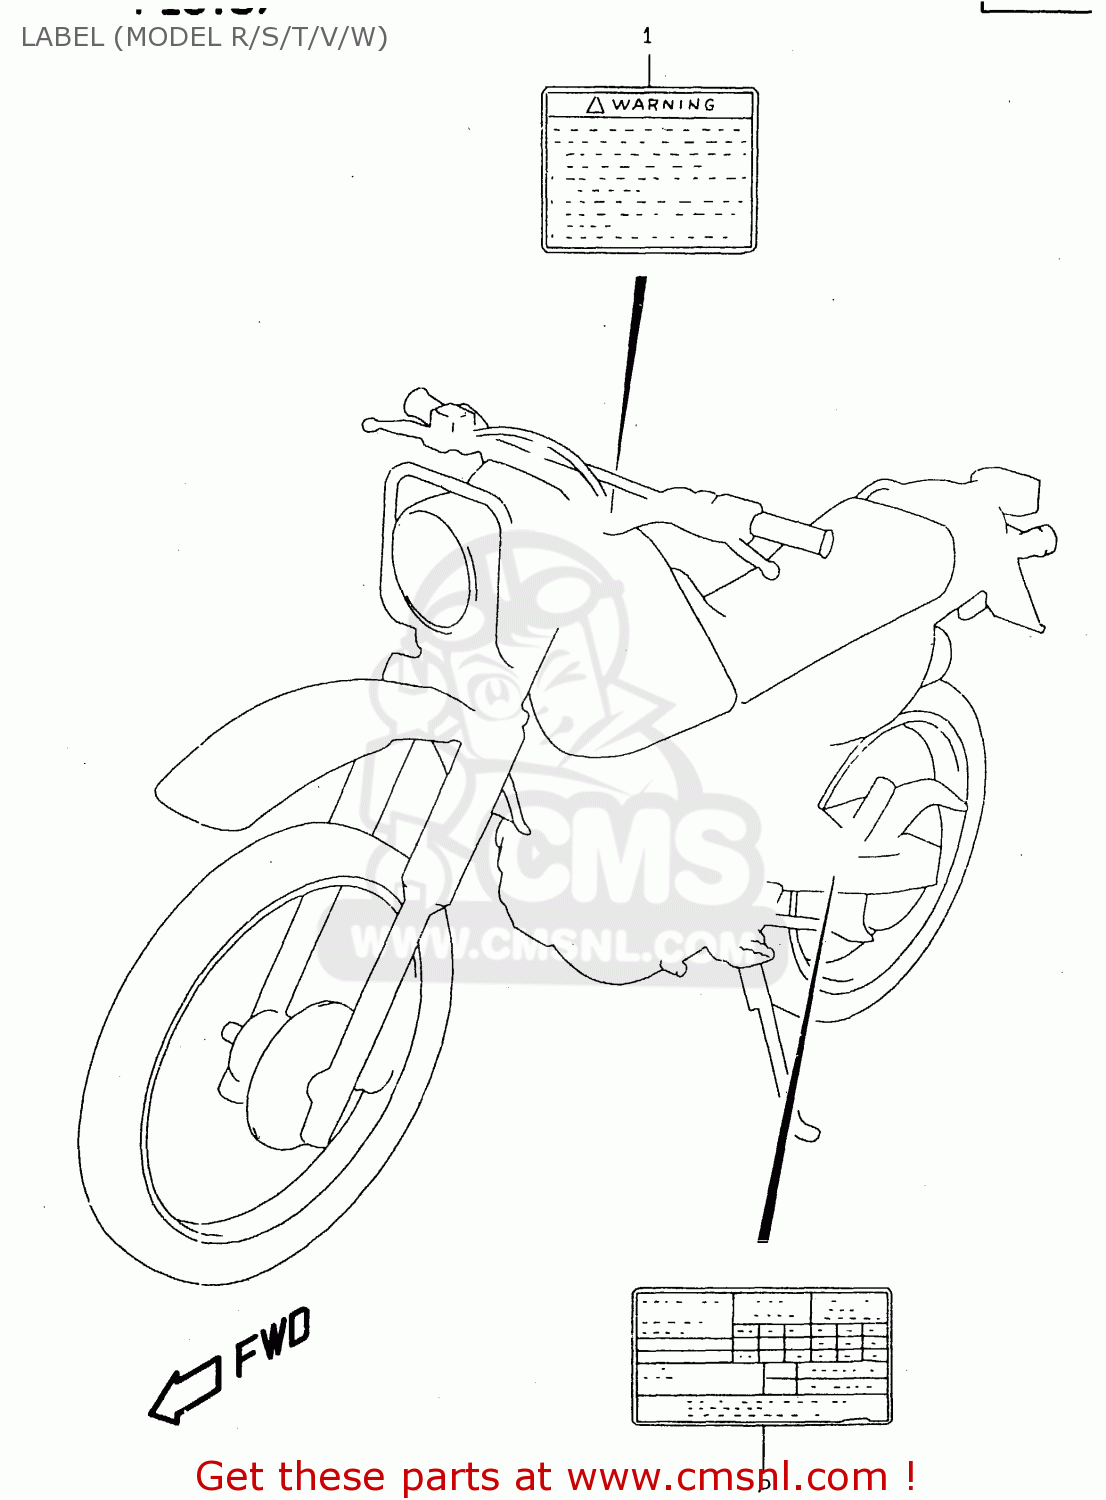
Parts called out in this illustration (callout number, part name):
1	LABEL
2	LABEL,TIRE INFORMATION
3	MANUAL, OWNER'S
